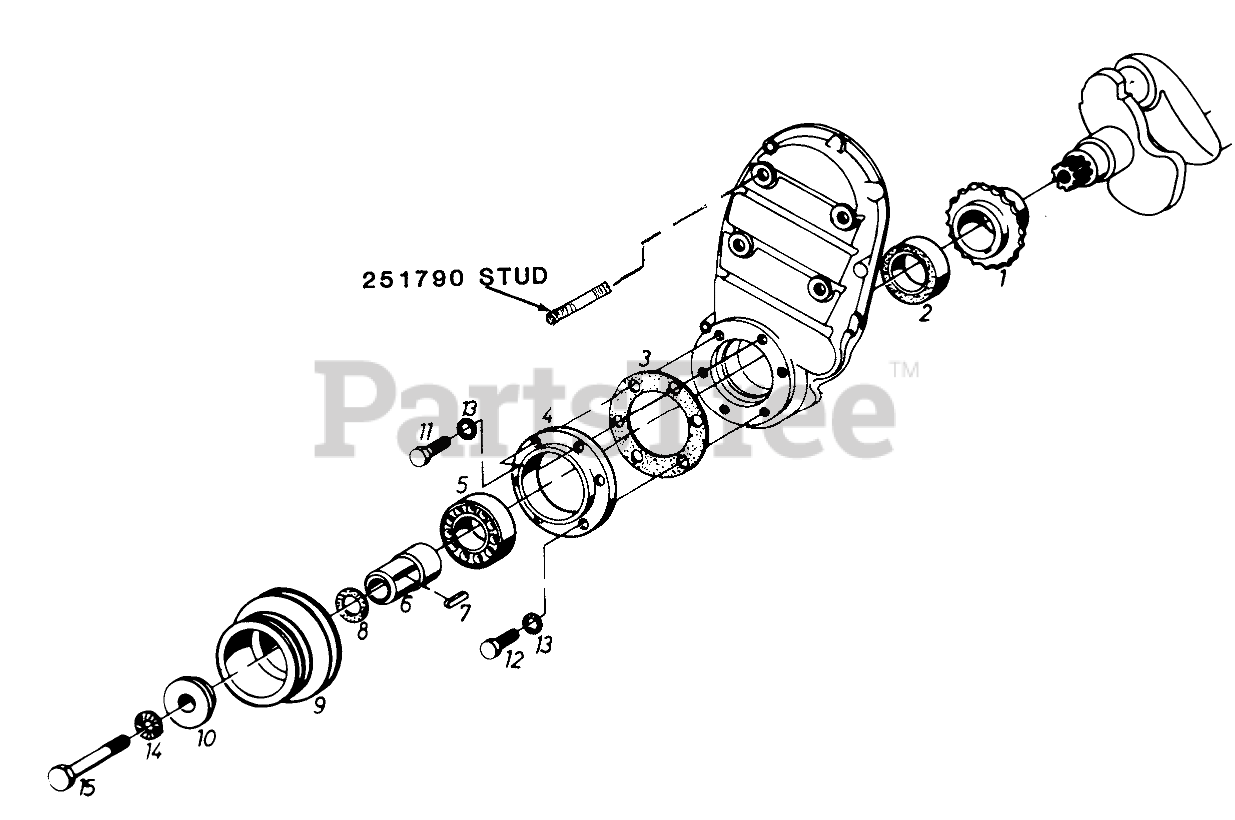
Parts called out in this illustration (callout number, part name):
1	CHAINE WHEEL
3	GASKET
4	Bearing Flange
5	Ball Bearing
6	Drive Sleeve
8	Gasket
10	Washer
12	Screw
13	Schnorr Washer
14	Schnorr Washer
15	Screw
